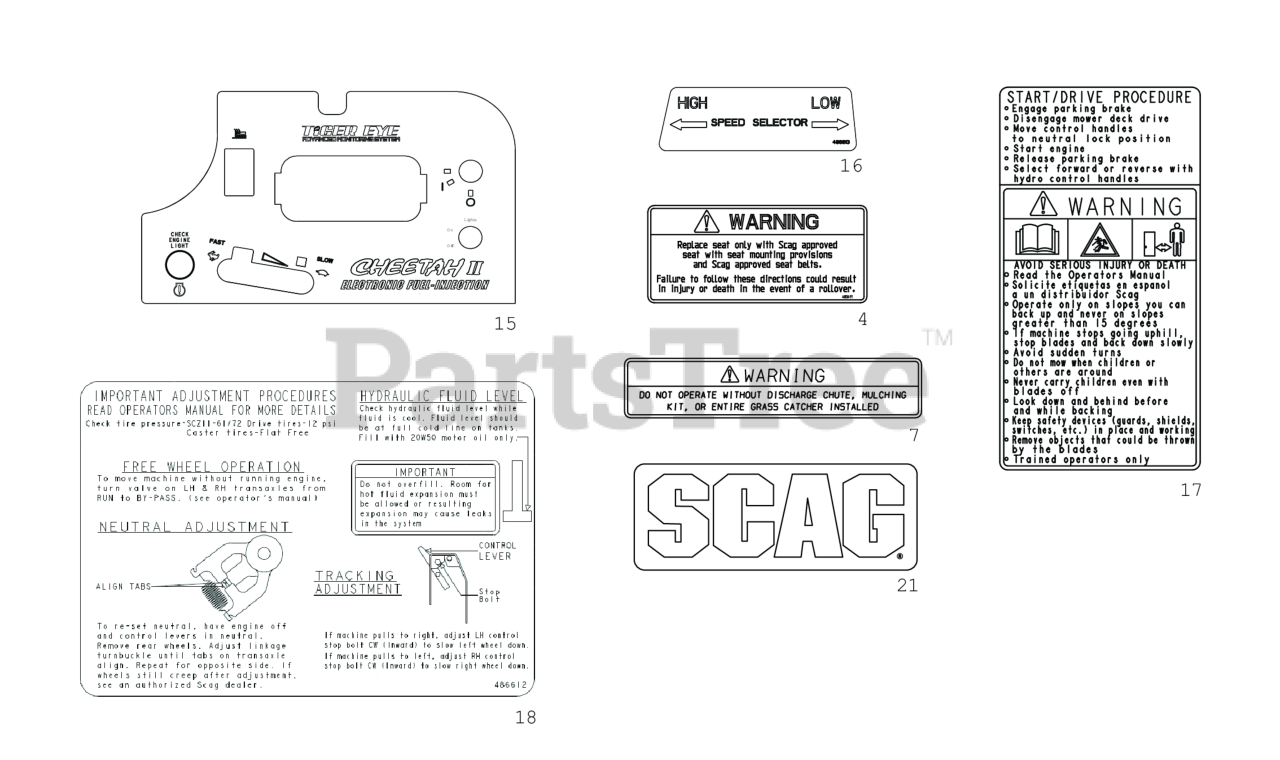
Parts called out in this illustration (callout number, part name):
4	Decal, Seat Replacement
7	Decal, Warning-Discharge
15	Decal, Instrument Panel - SCZII - EFI
16	Decal, Speed Control
17	Decal, Start / Drive
18	Decal, Adjustments - SCZII
21	Decal, Scag - Fuel Tank
